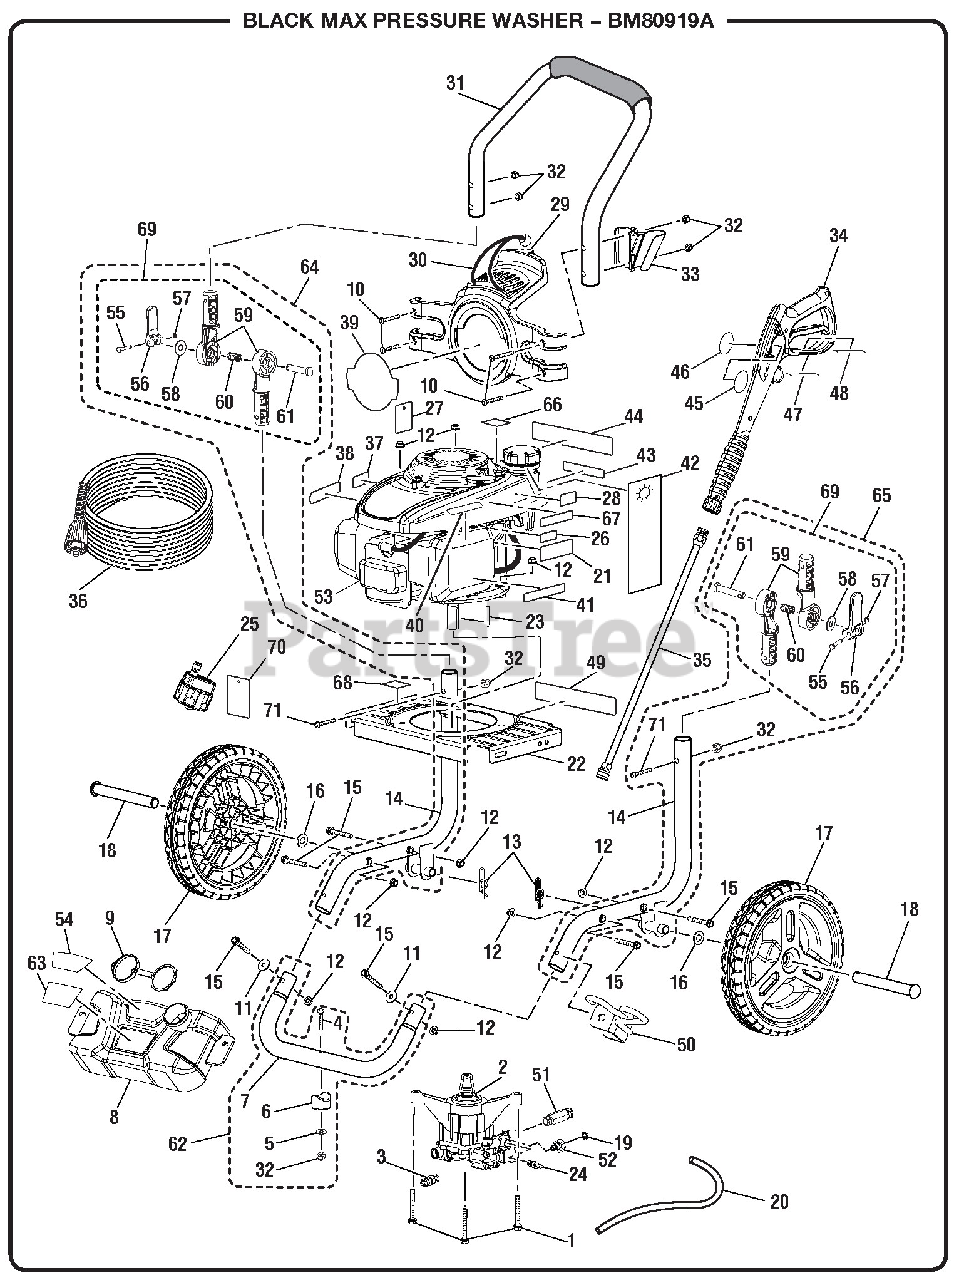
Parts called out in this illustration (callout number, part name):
1	Bolt (M8 x 60 mm, Flange Hd)
3	Thermal Release Valve
4	Screw (1/4-20 x 185 in, T30 Torx Hd)
5	Washer (1/4 in)
7	Front Frame
8	Soap Tank
9	Soap Tank Cap
10	Screw (1/4-20 x 227 mm, Pan Hd)
11	Washer (5/16 in)
12	Hex Nut (M8 x 1-1/4 in)
13	Ring Clip
14	Main Frame Assembly
15	Bolt w/Washer (M8 x 55 mm, Hex Hd)
16	Washer (1/2 in)
19	Filter Screen (Pump Inlet)
20	Chemical Siphon Tube
21	Choke Label
22	Engine Plate
23	Output Shaft Key (40 mm)
24	Detergent Suction Kit
25	6-in-1 Nozzle
26	Engine ON/OFF Label
27	Dipstick Hang Tag
28	Do Not Mix Label
29	Hose and Nozzle Holder Assembly
30	Bungee Cord and Bead Assembly
31	Handle w/Foam
32	Lock Nut (1/4-20)
33	Wand Holder
34	Trigger Handle Assembly
35	Extension Wand
36	Hose (25 ft, 3000 psi)
37	Lubricant Label
38	Hot Muffler Label
39	Performance Label
40	Inquires Label
41	EMC Label
42	Warning Hang Tag
43	UL Fire Warning Label
44	Warning Label
45	Wand Warning Label
46	Wand Logo Label
47	Warning Label
48	Wand Rating Label
49	Data Label
50	Wand Holder
51	Outlet Tube
52	Inlet Tube
54	Soap Dilution Label
56	Handle Lock Lever
59	Locking Pivot Bracket
61	Locking Cam Pin
62	Front Frame Assembly
63	Powered By Honda Label
64	Frame Assembly w/Lock Lever, Left
65	Frame Assembly w/Lock Lever, Right
66	E85 Label
67	Release Pressure Label
68	Engine Lubricant Label
69	Lock Lever Assembly
70	6-in-1 Nozzle Hang Tag
71	Screw (1/4-20 x 43 mm)
